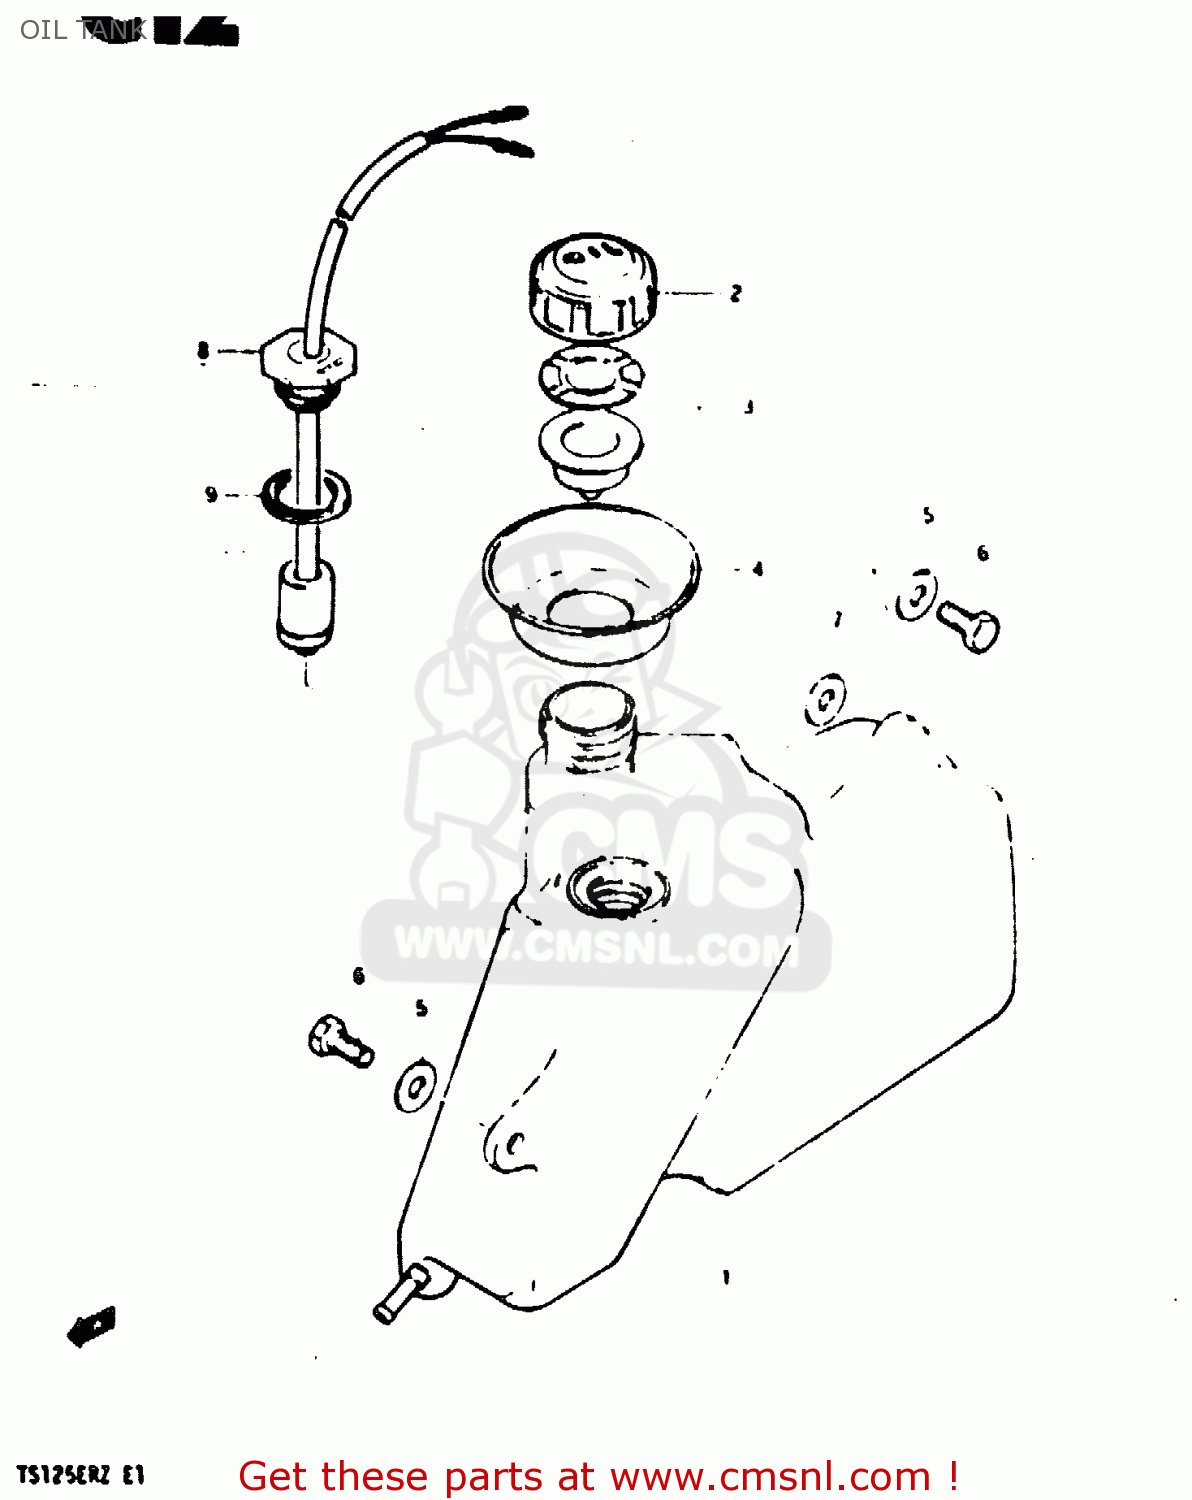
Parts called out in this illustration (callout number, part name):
1	TANK,OIL
2	CAP,OIL TANK
3	GASKET SET (NAS)
4	RUBBER,OIL TANK INLET
5	WASHER
6	BOLT, UPPER
7	WASHER
8	SWITCH ASSY, OIL LEVEL
9	GASKET (NAS)
